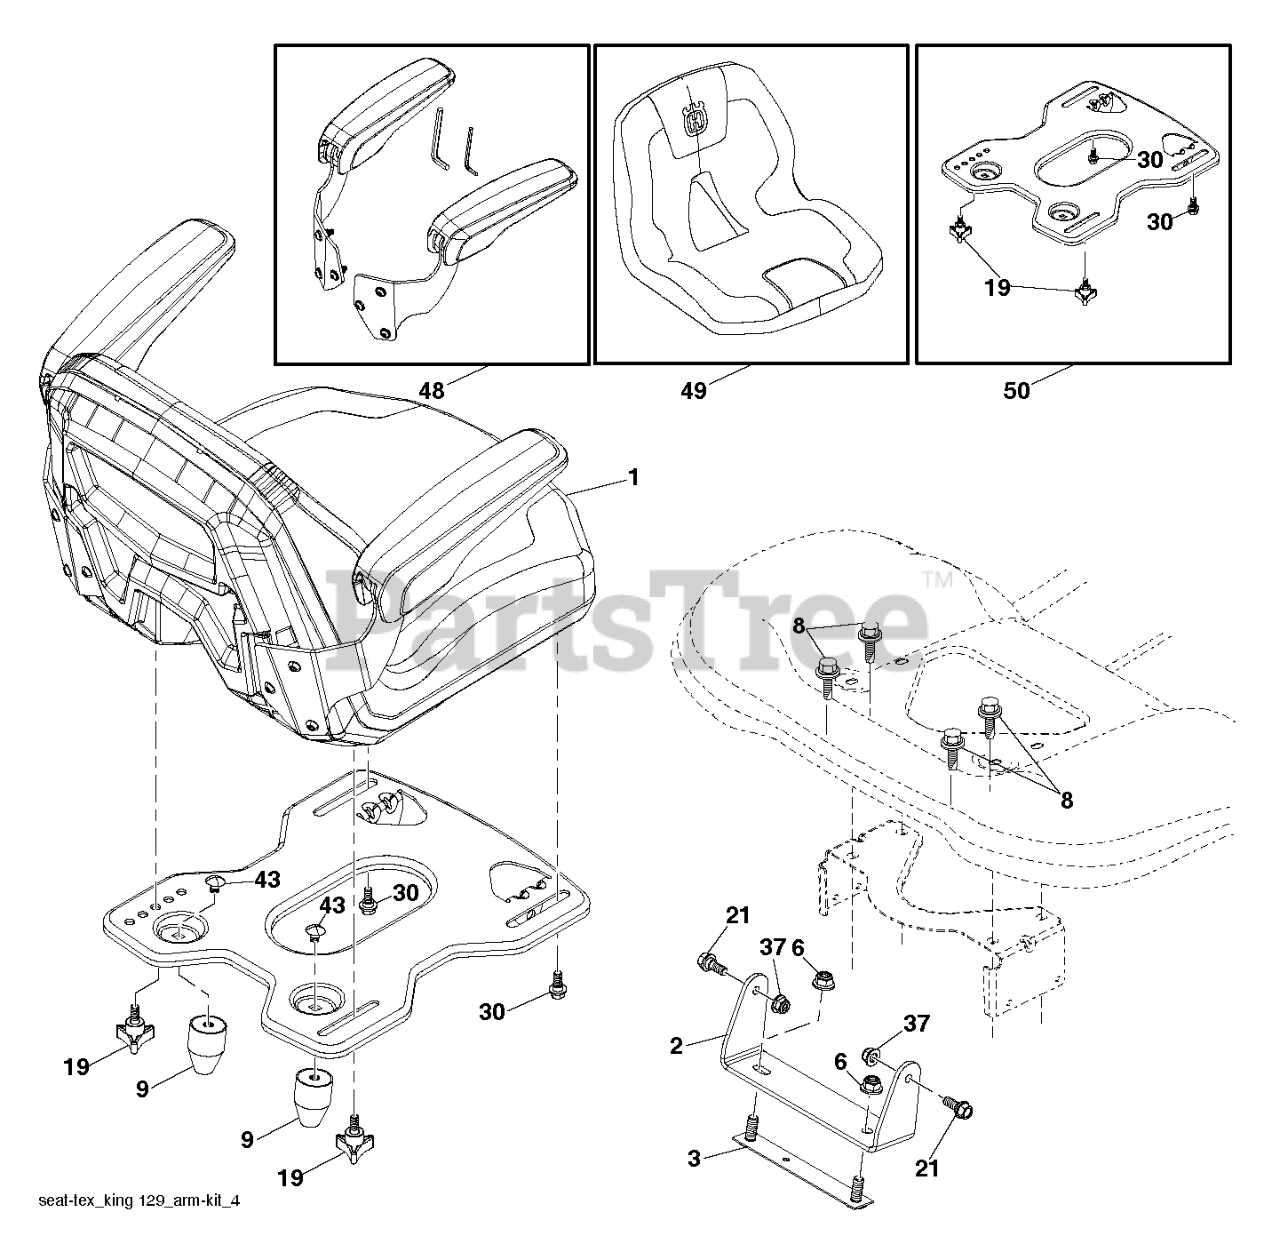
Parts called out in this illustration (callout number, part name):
3	BRACKET ASSEMBLY REINFORCEMENT
8	BOLT.5/16-18UNCX3/4 W/SEMS.BLK
19	GSPW Knobs
37	NUT HEXAGON FLANGE 5/16-18 ST
48	ARMREST KIT
50	Service Kit
